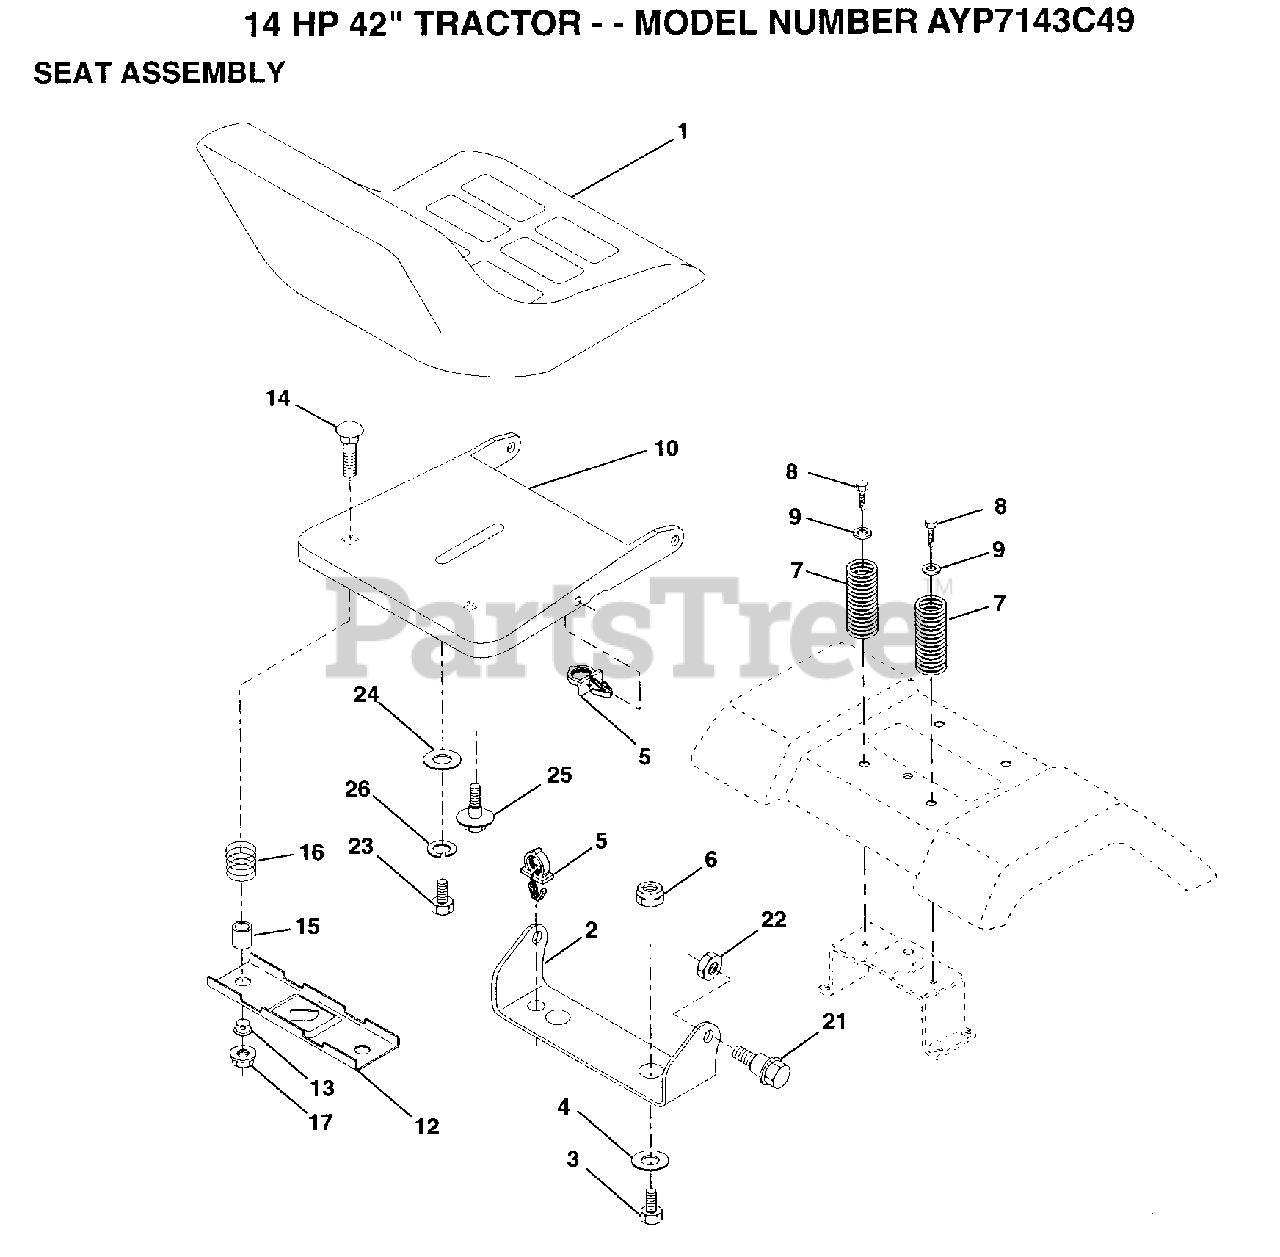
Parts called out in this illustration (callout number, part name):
2	BRACKET PVT SEAT
3	BOLT
4	WASHER PM
5	CLIP PUSH - IN
6	NUT
7	SPRING COMPRESSIO
8	SCREW GTV
9	WASHER
12	BRKT SWITCH
13	BUSHING
15	SPLIT SPACER
16	SPRING
21	BOLT.SHLD.5/16-18
23	BOLT
24	WASHER
25	"BOLT,SHOULDER"
26	LOCKWASHER
